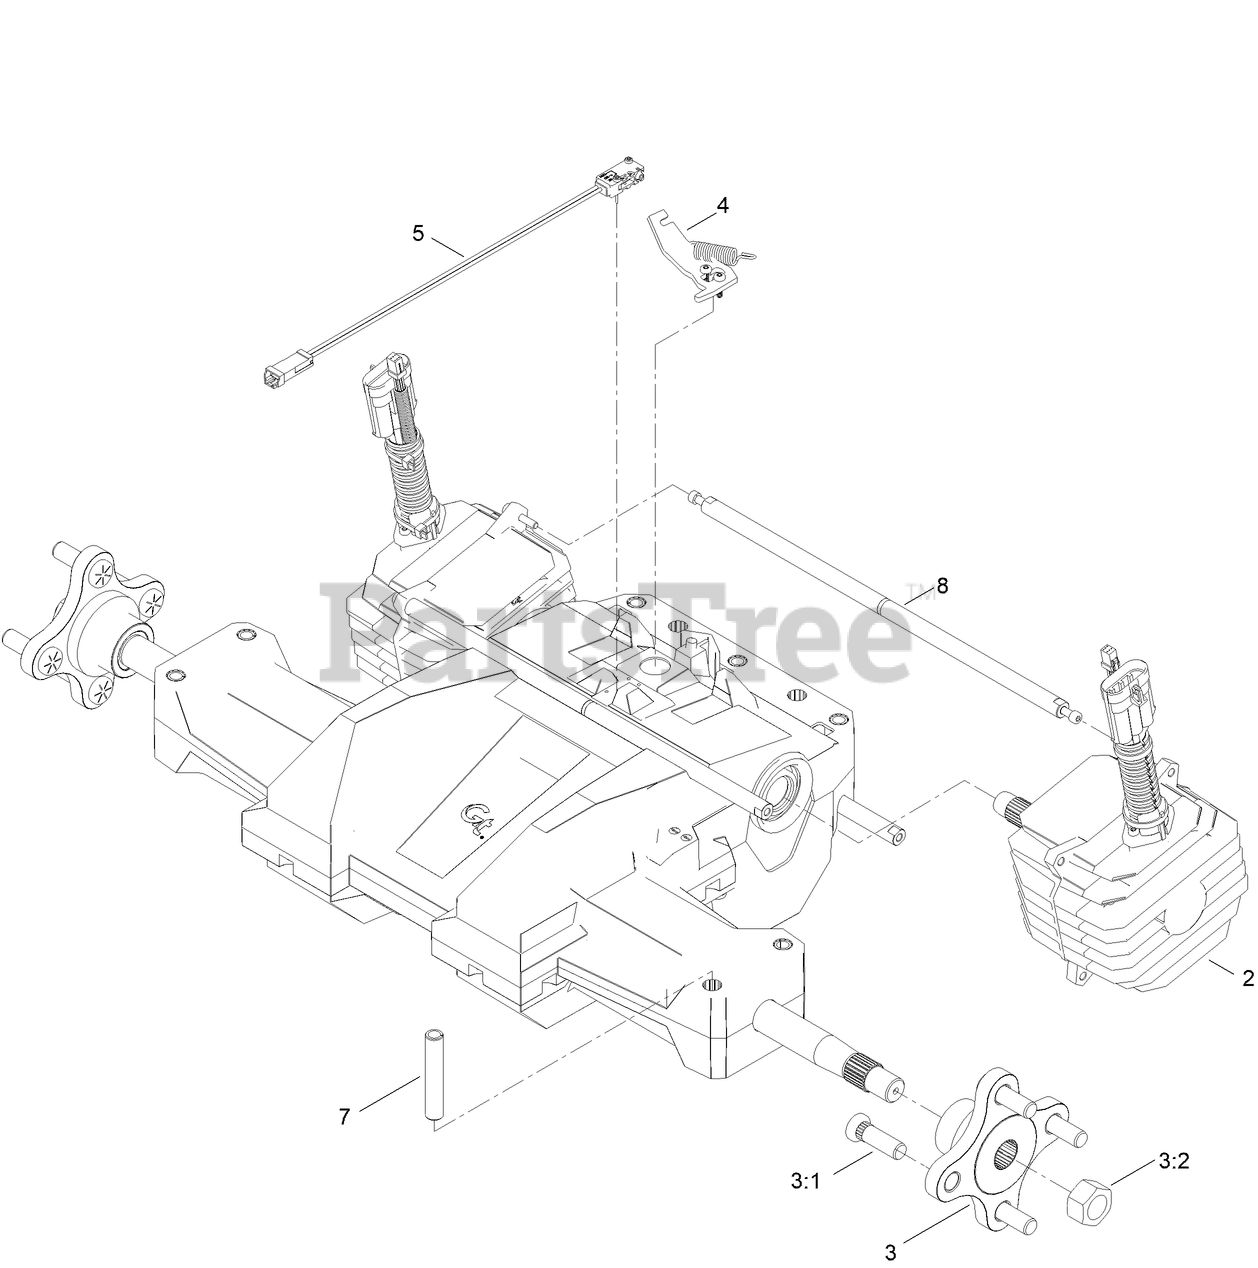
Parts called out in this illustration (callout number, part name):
2	MOTOR ASM
3	WHEEL HUB ASM
3:1	STUD-WHEEL
3:2	NUT-HUB
4	ARM-BRAKE ASM
5	SWITCH-BRAKE ASM
7	SPACER
8	ROD-CROSS
